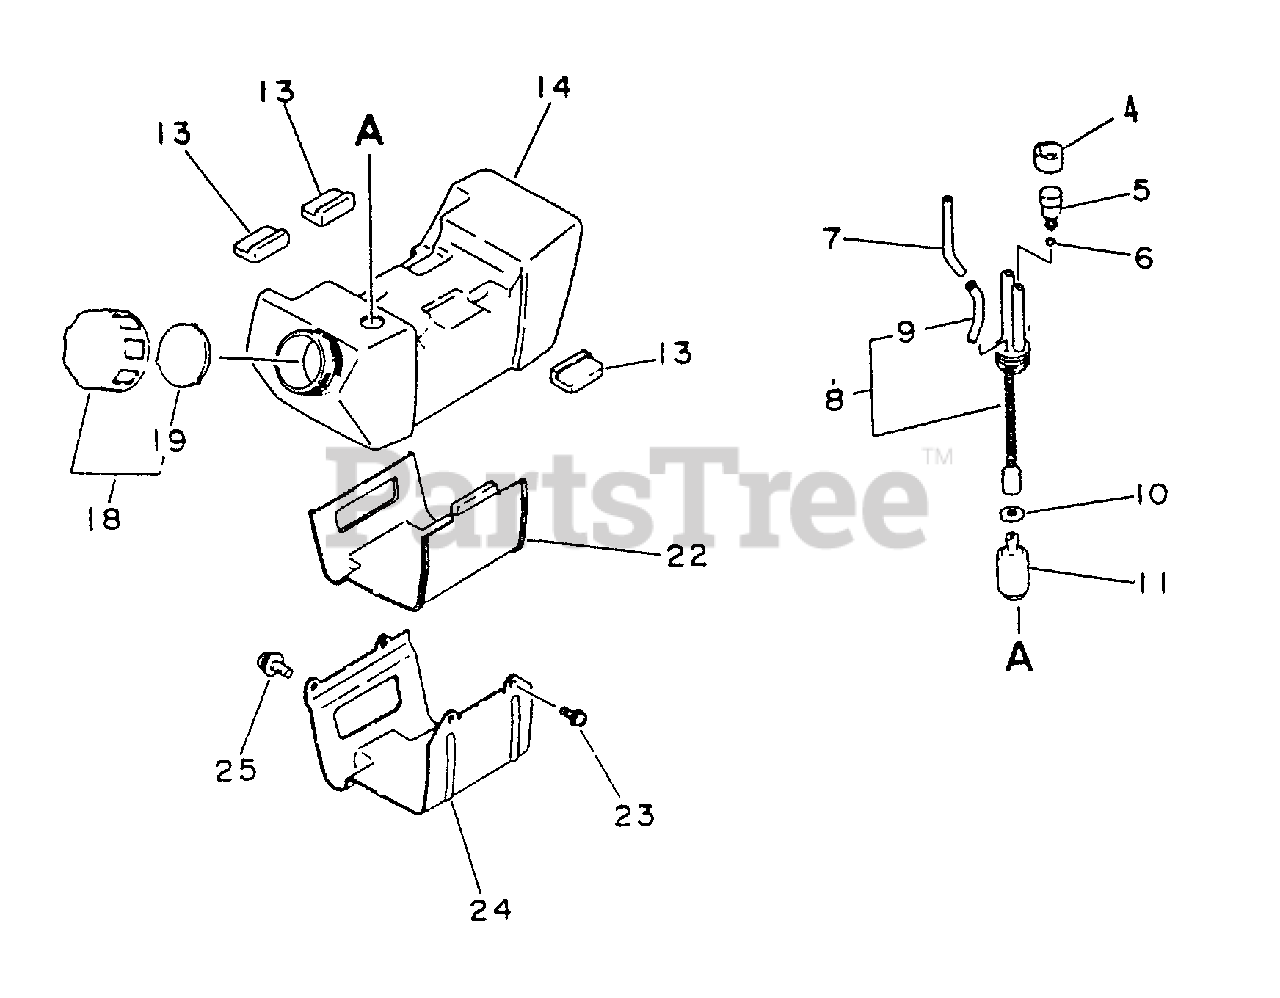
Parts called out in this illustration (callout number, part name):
4	HOLDER, VENT
5	VENT ASSY
7	PIPE, FUEL 3×6×50
8	PIPE, FUEL
9	CONNECTOR, PIPE
10	WASHER 5.5×12×0.8
11	FILTER, FUEL
14	TANK, FUEL
18	CAP ASSY
19	GASKET, FUEL CAP
23	SCREW 4×10
24	BRACKET, FUEL TANK
25	SCREW 5×12
